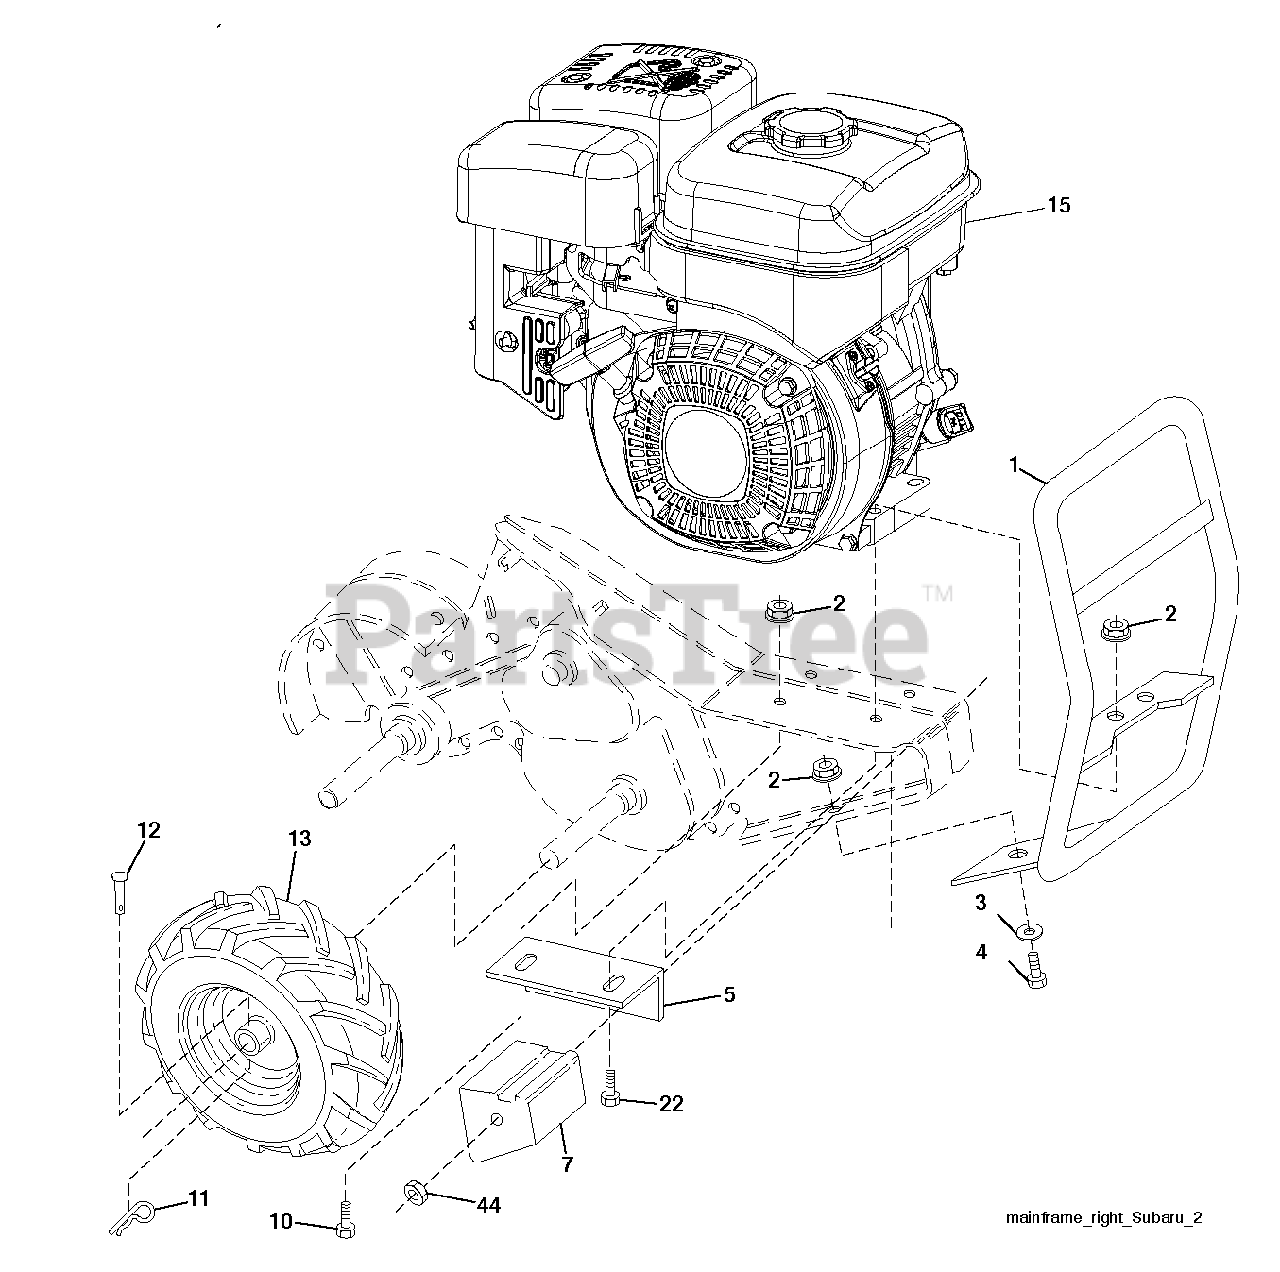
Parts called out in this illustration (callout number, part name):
1	BUMPER.ASM.TILLER.
2	LOCKNUT-FLANGE 5/16-18
3	WASHER
4	BOLT
5	DNO BRACKET RH CRT
7	COUNTERWEIGHT, RH
10	BOLT
11	RETAINER M
12	RIVET,DRILLED
13	TIRE.16X4-8.CHEVRON.TILLER
22	BOLT, HEX 5/16-18X1-3/4
